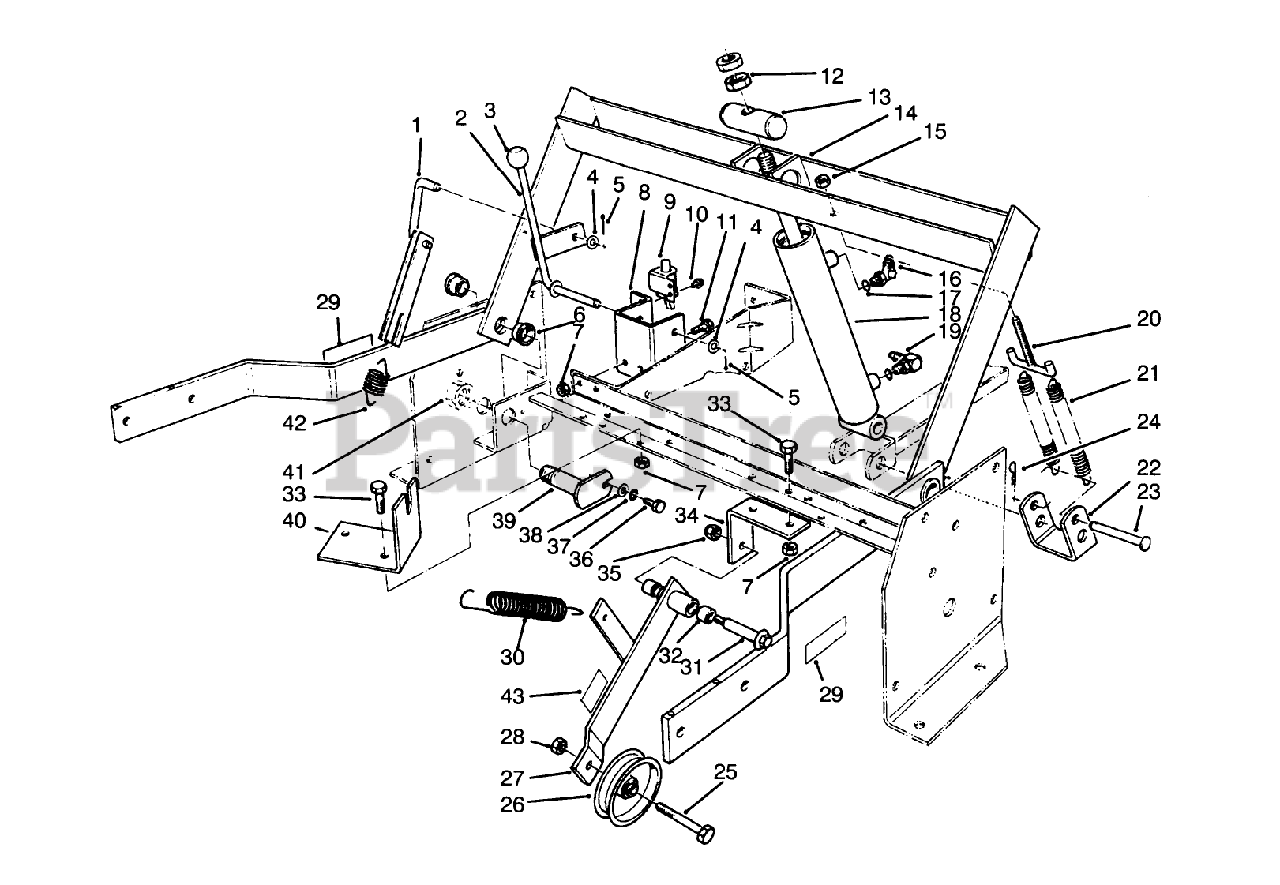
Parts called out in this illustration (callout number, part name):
1	Link-Parking Brake
2	Brake Lever
4	WASHER-FLAT
5	PIN-COTTER
6	BEARING-FLANGE
7	NUT-LOCK, NI
8	Bracket-Parking Brake
9	SWITCH-BRAKE, PARKING
10	SCREW-TAPTITE
11	SCREW-HH
12	NUT-JAM
13	CYL.PIVOT PIN
14	Frame-Lift (Incl. Ref. #6)
15	NUT-HEX, SIDE DEFORM
16	FITTING-45 DEG
17	O-RING
18	CYLINDER - LIFT
19	FITTING-ELBOW, 90
20	T-HOOK W A
21	SPRING_EXTENSION
22	SPRING BRACKET
23	PIN-CLEVIS
24	PIN-HAIR
25	SCREW-HH
26	PULLEY-IDLER
27	Lever-Idler (Incl. Ref. #43)
28	NUT-LOCK, NI
29	WARNING DECAL
30	IDLER EXT SPRING
31	BOLT-WHEEL
32	BUSHING
33	SCREW-HH
34	JACKSHFT IDLR BRKT
35	NUT-LOCK
36	SCREW-HH
37	WASHER-LOCK
38	WASHER-FLAT
39	Pin-Pivat
40	TRACT CABLE BRKT
41	NUT-LOCK, NI
42	PARK BRAKE SPRING
43	DECAL-WARNING
